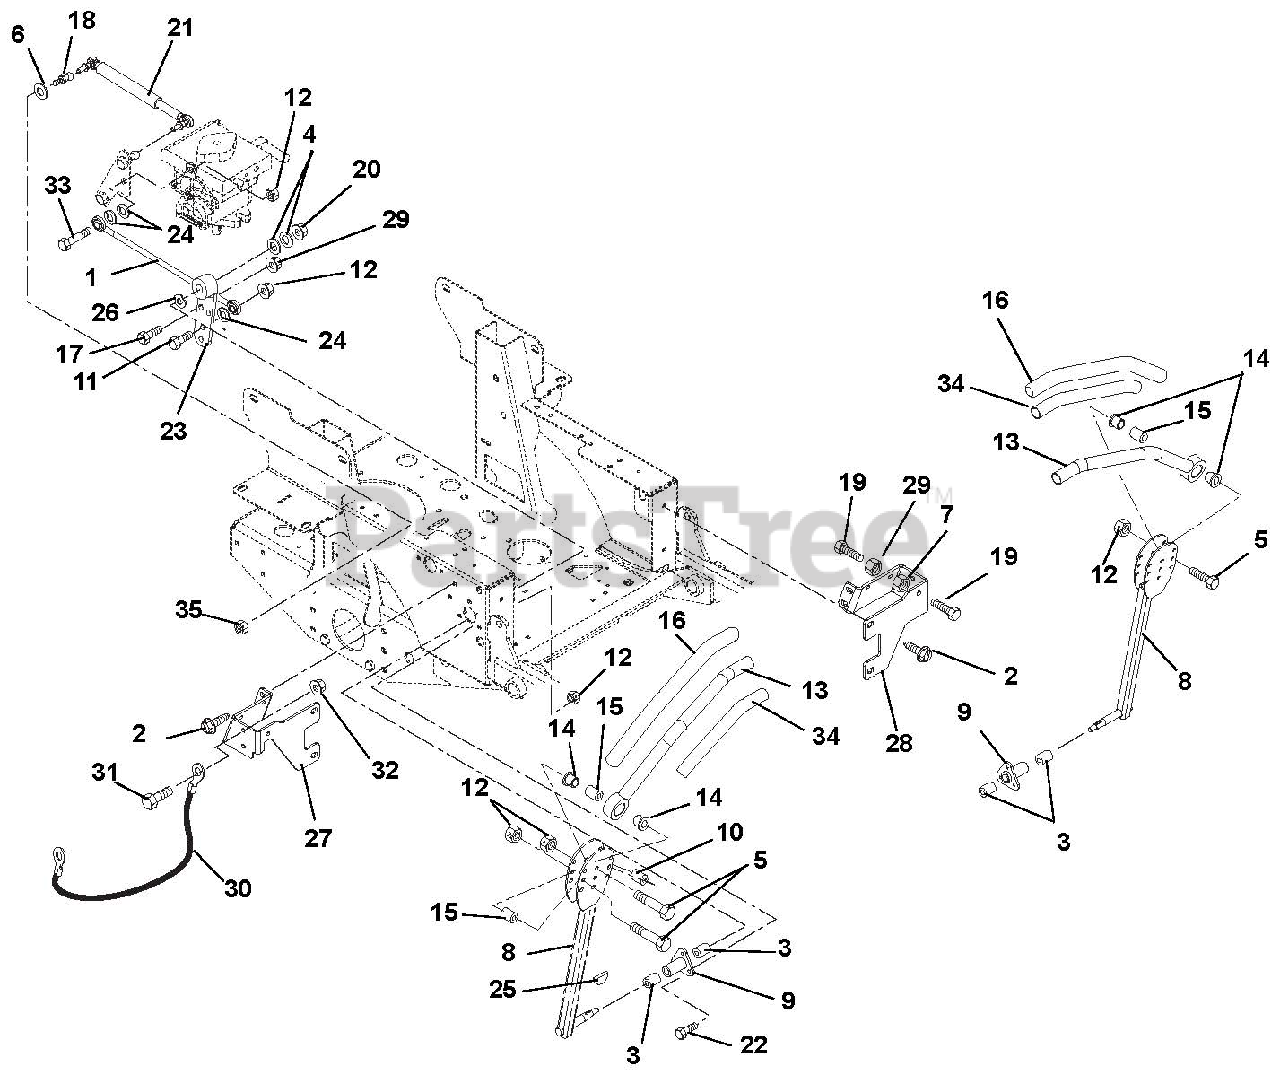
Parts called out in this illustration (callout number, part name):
1	Assembly, Steering Rod
2	Screw, Tapping .38-16 x .75 Hex Washer Head
3	Bushing .625 x .75 x .50
4	Washer, Flat Steel .406 x .812 x .065
5	Bolt, Hex .31-18 x 1.75 Grade 5
6	Washer, Flat Steel .344 x .065 YWZC
7	Nut, Hex Jam .375-16
8	Control Arm
9	Housing, Bushing
10	Bushing, Eccentric .31 x .75 x .97
11	Bolt, Hex .31-18 x 1.25 Grade 5
12	Nut, Nyloc Flange .375-16
13	Handle Weldment, Left Hand
13	Handle Weldment, Right Hand
14	Bushing, Flange Nylon .762 x 1.48 x .44
16	Grip, Handlebar
17	Bolt, Hex .375-16 x 1.75
18	Stud, Ball
19	Bolt, Hex .38-16 x 1.25 Grade 5
20	Nut, Nyloc Flange 3/8-16
21	Damper
22	Bolt, Hex .31-18 x 1.00 Grade 5
23	Weldment, Pivot Arm
24	Washer, Locking .31 x .078 Regular
25	Key, Woodruff .13 x .63
26	Wave Washer
27	Stop, Steering, Right Hand
28	Stop, Steering, Left Hand
29	Nut, Locking Jam Center .375-16
30	Cable, Hood
31	Bolt, Hex .25-20 x .75 Grade 5
32	Nut, Nyloc Flange .25-20
33	Bolt, Hex .31-18 x 1.50 Grade 5
34	Tube, .88ID x 1.00OD x 10.75
35	Nut, Top Lock .31-18
